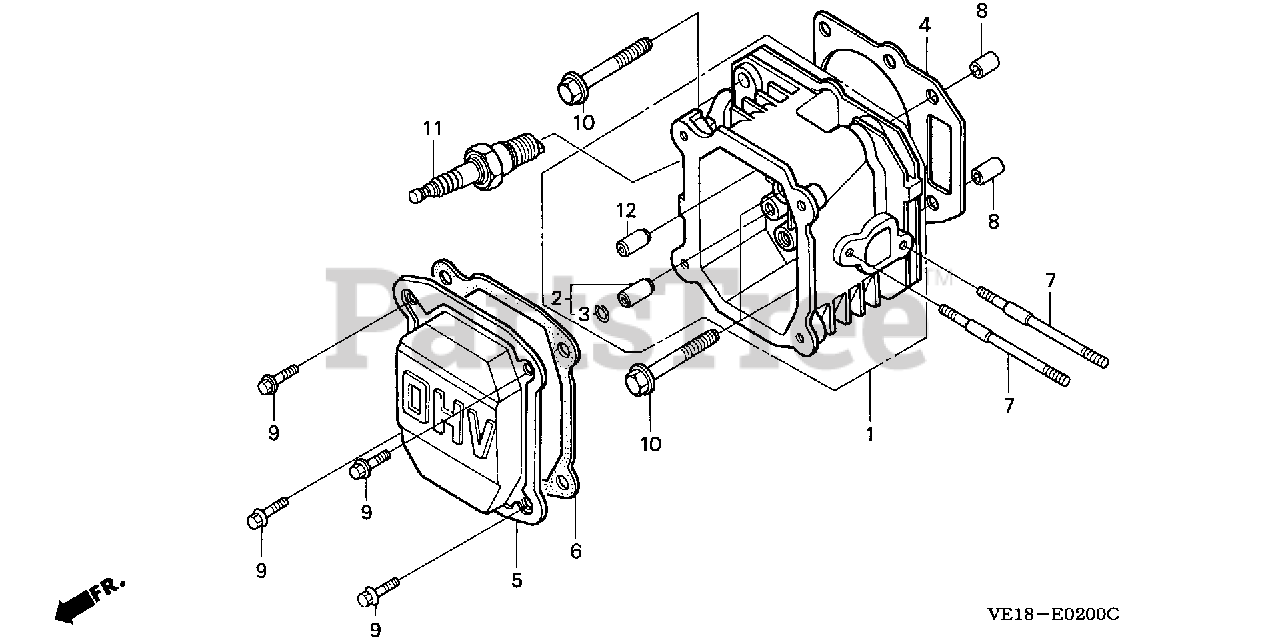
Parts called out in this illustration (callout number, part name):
1	CYLINDER HEAD (USA)
2	GUIDE, EX. VALVE (OVER SIZE)
3	CLIP, VALVE GUIDE
4	GASKET, CYLINDER HEAD
5	COVER, HEAD
6	GASKET, HEAD COVER
7	BOLT, STUD (6X83)
8	PIN, DOWEL (10X16)
9	BOLT, FLANGE (6X14)
10	BOLT, FLANGE (8X50)
11	SPARK PLUG (BPR4ES) (NGK)
11	SPARK PLUG (BPR5ES) (NGK)
11	SPARK PLUG (BPR6ES) (NGK)
12	GUIDE, VALVE (OVER SIZE)
